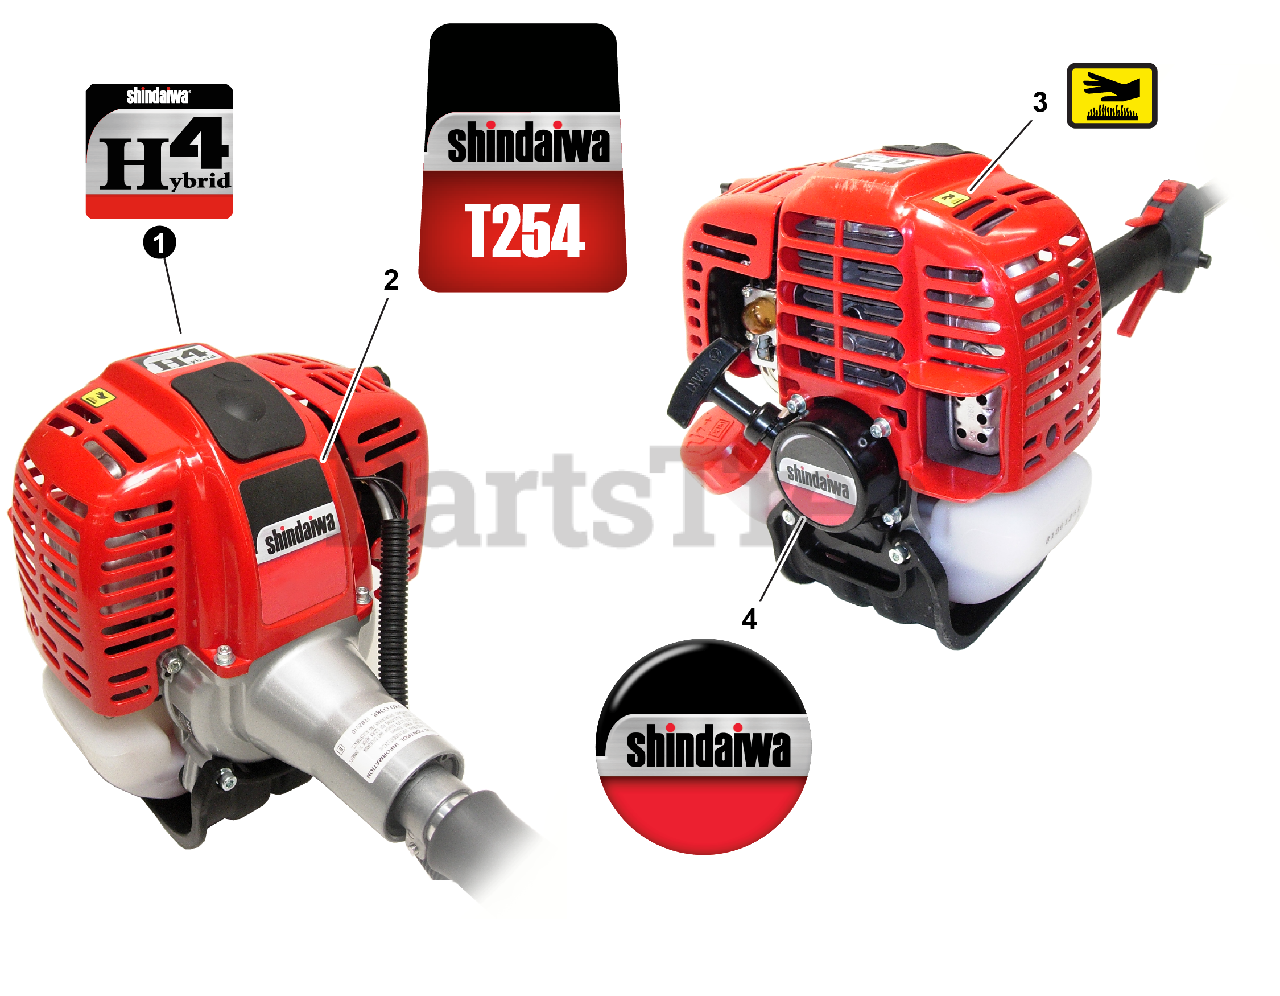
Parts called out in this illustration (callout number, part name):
1	LABEL, shindaiwa H4
2	LABEL - MODEL T254
3	LABEL, CAUTION - HOT
4	LABEL, RECOIL STARTER
